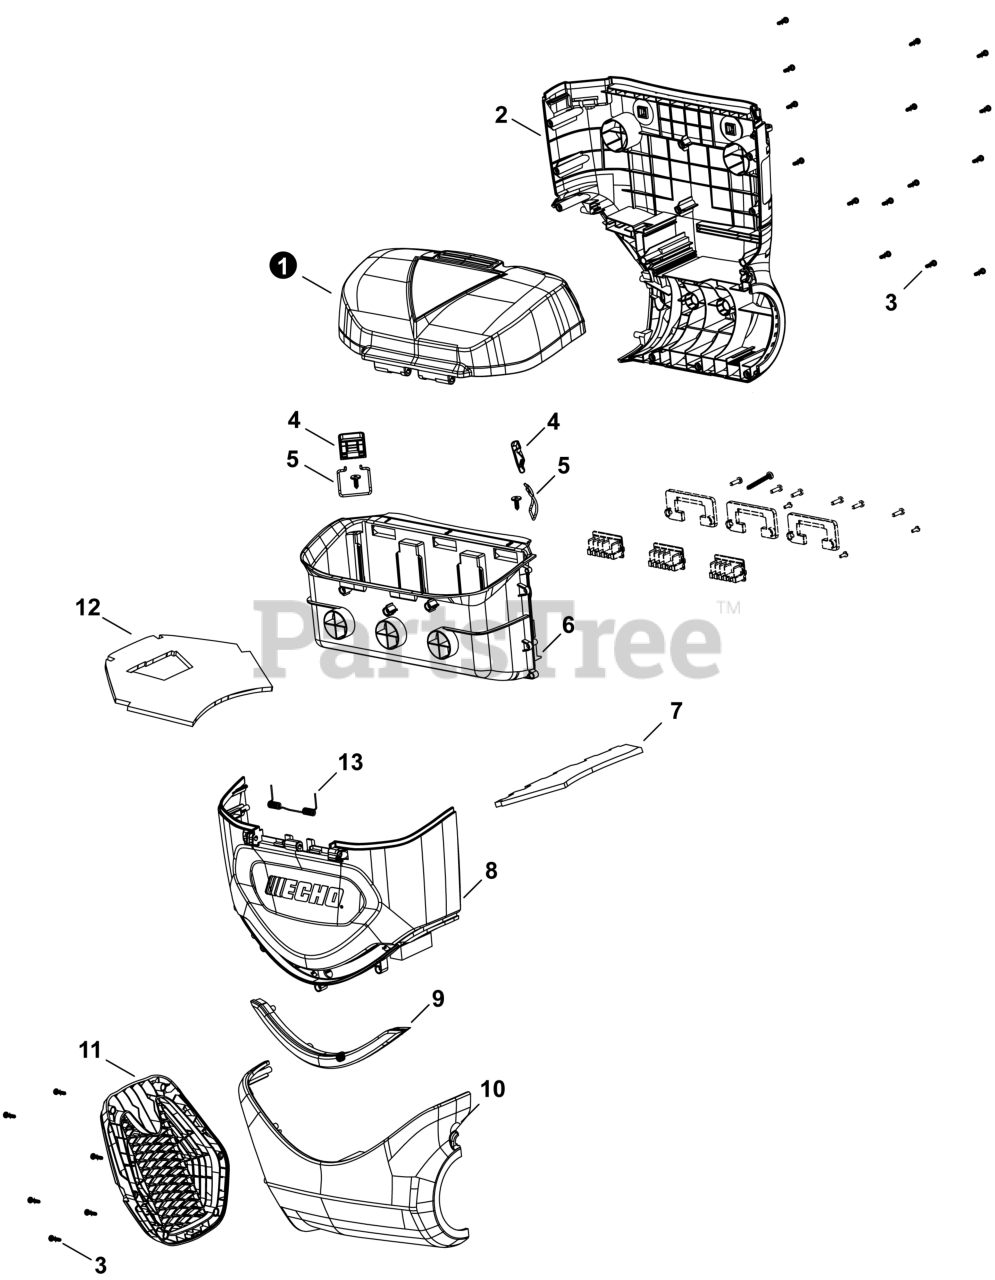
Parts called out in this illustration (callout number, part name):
1	COVER, BATTERY COMPARTMENT
2	HOUSING, REAR
6	HOUSING, BATTERY
7	INSULATION, LOWER
8	COVER, FRONT
9	LIGHT ASSY., SAFETY
10	HOUSING, FRONT MOTOR
11	COVER, AIR INTAKE
12	INSULATION, UPPER
